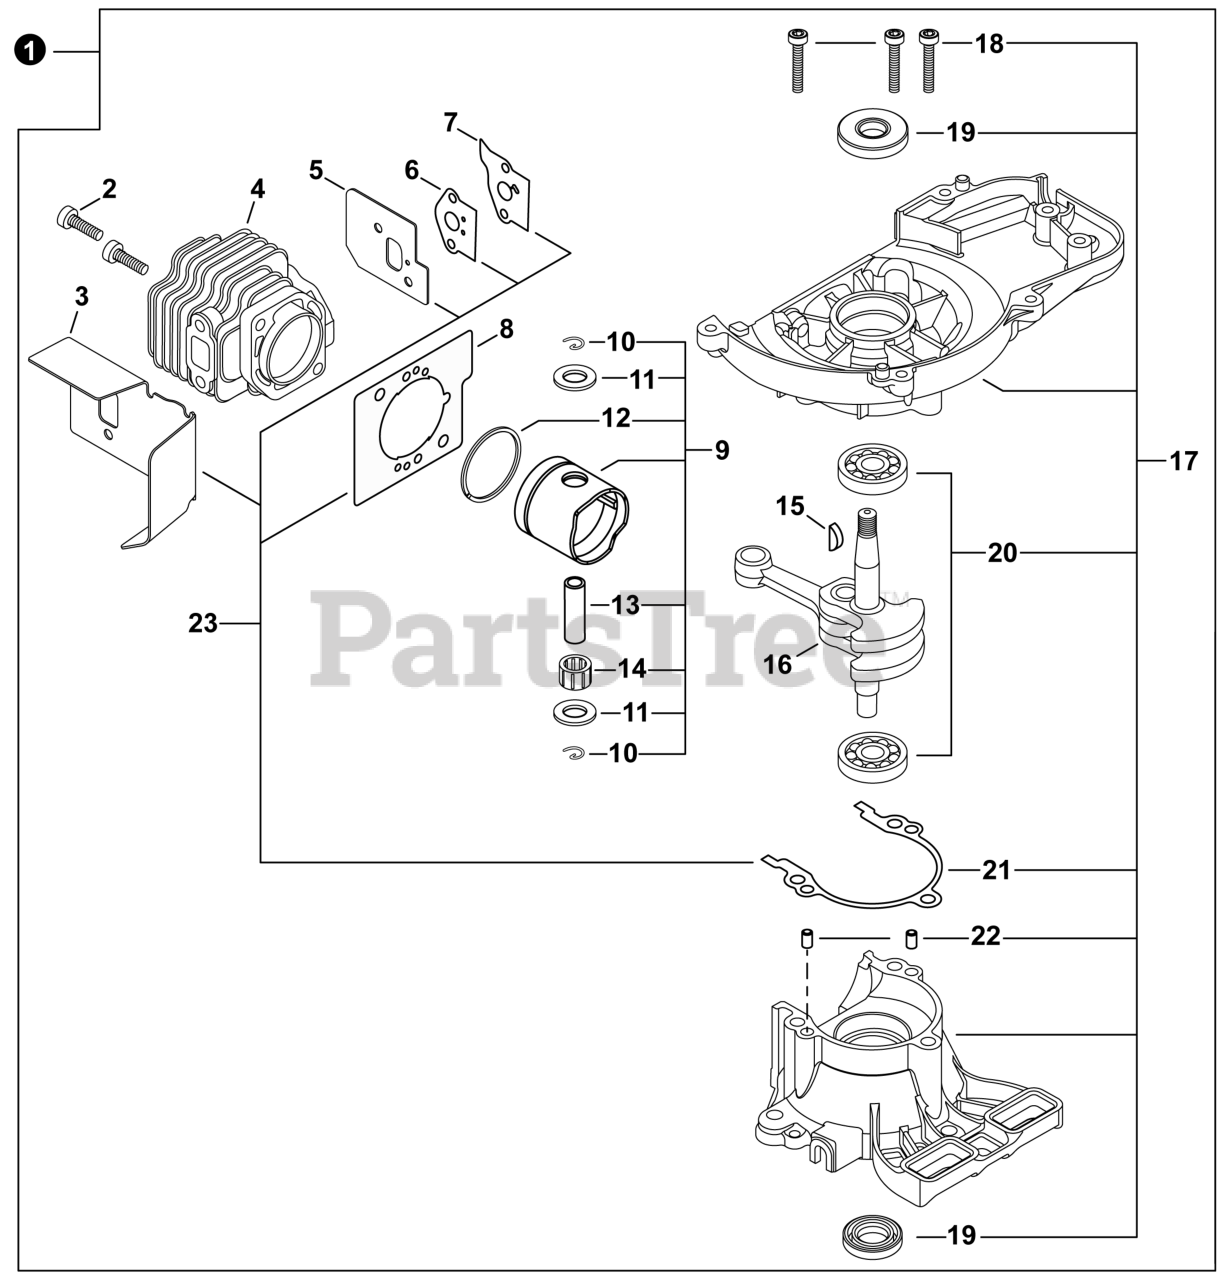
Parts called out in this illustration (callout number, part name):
1	SHORT BLOCK
2	BOLT, TORX 5x20
3	HEAT SHIELD, EXHAUST
4	CYLINDER
5	GASKET, INTAKE
6	GASKET, INTAKE
7	GASKET, INTAKE
8	GASKET, CYLINDER
9	PISTON KIT
10	RING, SNAP
11	WASHER, THRUST
12	RING, PISTON
13	PIN, PISTON 8
14	BEARING, NEEDLE
15	KEY, WOODRUFF
16	CRANKSHAFT ASSY
17	CRANKCASE SET
18	BOLT, TORX 5x25
19	SEAL, OIL
20	BEARING, BALL
21	GASKET, CRANKCASE
22	PIN, LOCATING 4x8
23	GASKET KIT
